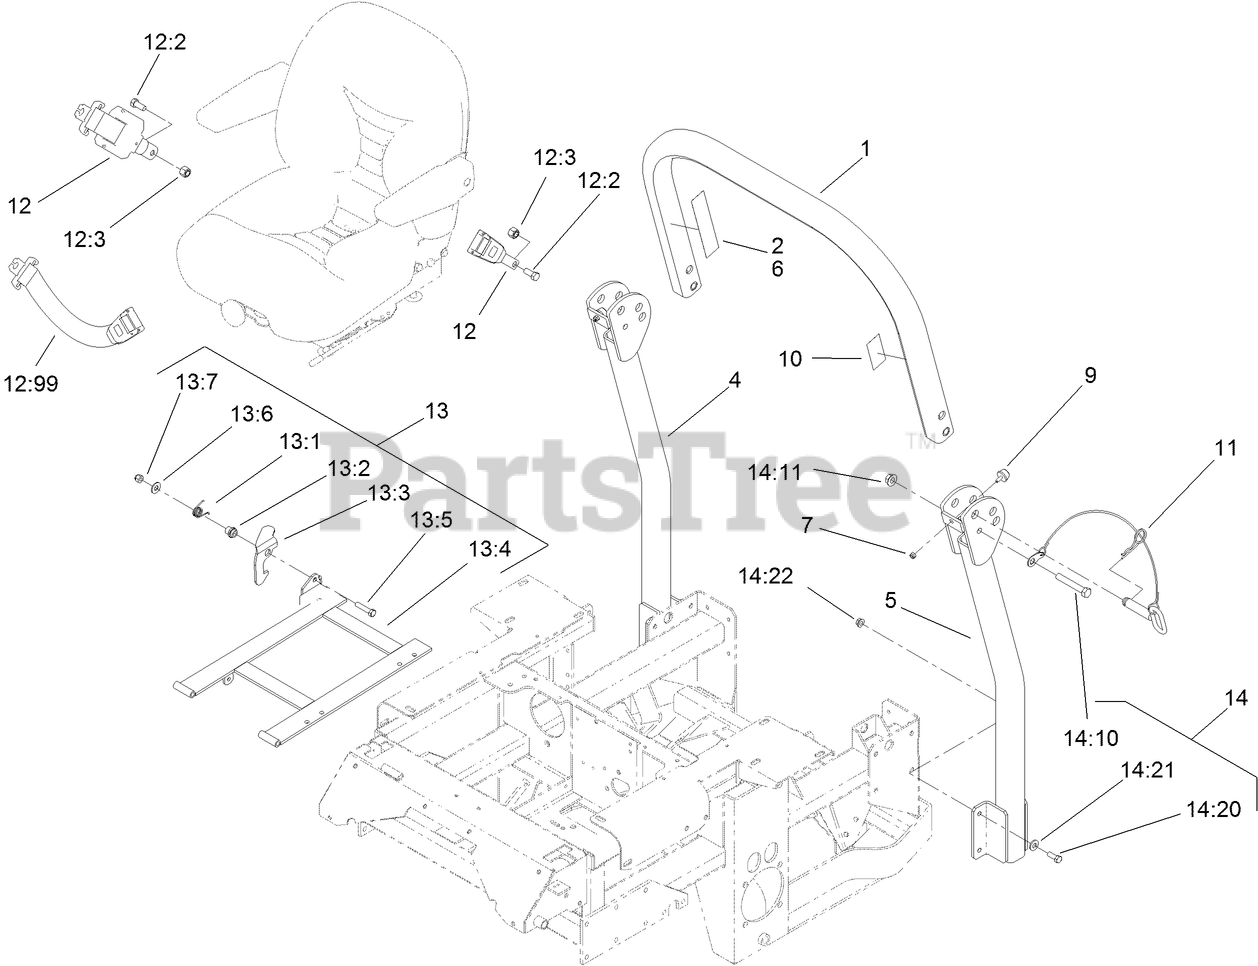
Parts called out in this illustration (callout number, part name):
1	Upper Tube ASM
2	DECAL-WARNING, FOLDING ROPS
4	TUBE-SUPPORT, RH
5	TUBE-SUPPORT, LH
6	DECAL-WARNING
7	NUT-LOCK, NI
9	BUMPER-RUBBER
10	DECAL-ROPS
11	PIN-FOLD, ROPS
12	RETRACTABLE SEATBELT KIT
12:2	SCREW-HH
12:3	NUT-LOCK
12:99	SEAT BELT EXTENSION KIT
13	SEAT FRAME SINGLE LATCH ASM
13:1	CATCH-LATCH, SINGLE
13:2	SPRING-TORSION, LATCH
13:3	BUSHING-LATCH, SEAT
13:4	FRAME-SEAT
13:5	WASHER-FLAT
13:6	NUT-LOCK, NI
13:7	SCREW-HH
14	BAG-BOLT
14:10	SCREW-HH
14:11	NUT-HF
14:20	SCREW-HH
14:21	WASHER-BELLEVILLE
14:22	NUT-HHF, WHIZ
